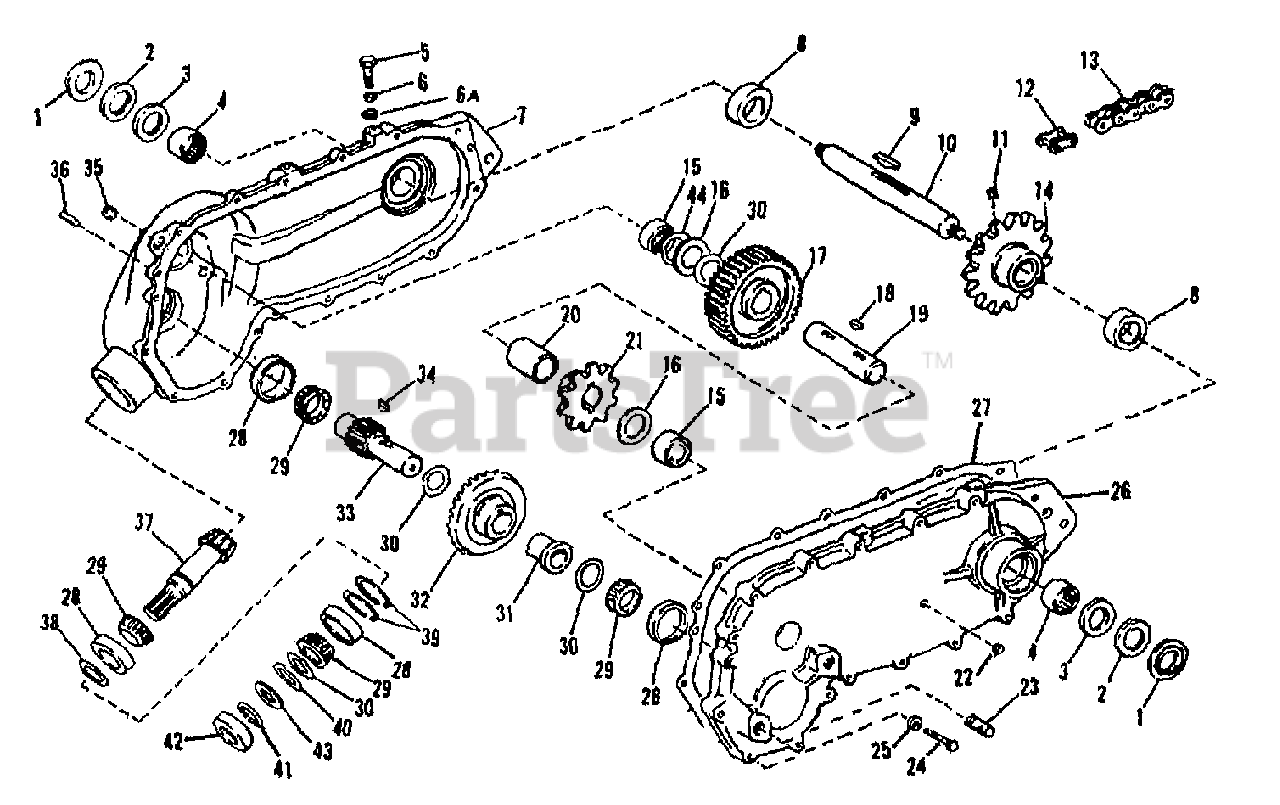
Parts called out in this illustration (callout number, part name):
1	WASHER-SEAL
2	SEAL-OIL
3	SEAL-OIL 1.25
4	BEARING-NEEDLE
5	SCR-HH 1/2-13X1.25 G5 ZP
6	WASHER-LK .5
6A	WASHER-1.06X.531X.1 ZP
8	WASHER-THRUST 2X1.27X.433
9	KEY-HI PRO .31X2.0
10	SHAFT-TINE
11	SCR-SET 3/8-16X1/2
12	CHAIN-ROLLER CONNECTOR
13	CHAIN-ROLLER 1 PITCH
14	SPROCKET-15 TOOTH 1"PITCH
15	BEARING-NEEDLE
16	WASHER-THRUST 2X1.27X.063
17	GEAR-39 TOOTH
18	KEY-.312 SQ X 1.063
19	SHAFT
20	SPACER-1.375X1.25X1.41
21	SPROCKET-10TOOTH 1"PITCH
22	PLUG-PIPE 1/8 NPT
24	SCR-HH 5/16-18X2.25 G5ZP
25	WASHER-LK .312 ZP
26	COVER-GEAR CASE
27	GASKET
28	BEARING-CUP
29	BRG-TAPERED ROLLER CONE
30	SHIM-.005
31	SPACER-1.625X1.25X1.225
32	GEAR-BEVEL 40 TOOTH
33	SHAFT AND PINION
34	KEY-WOODRUFF .25X1
35	PLUG-PIPE
36	PIN-DRIVE .375X1.00 ZP
37	PINION-13 TOOTH
38	SHIM-2.313X1.87X.005
39	RING-RETAINING
40	WASHER
41	RING-RET
42	SEAL-OIL
43	THRUST-RACE
44	SHIM-1.75X1.26X.02
